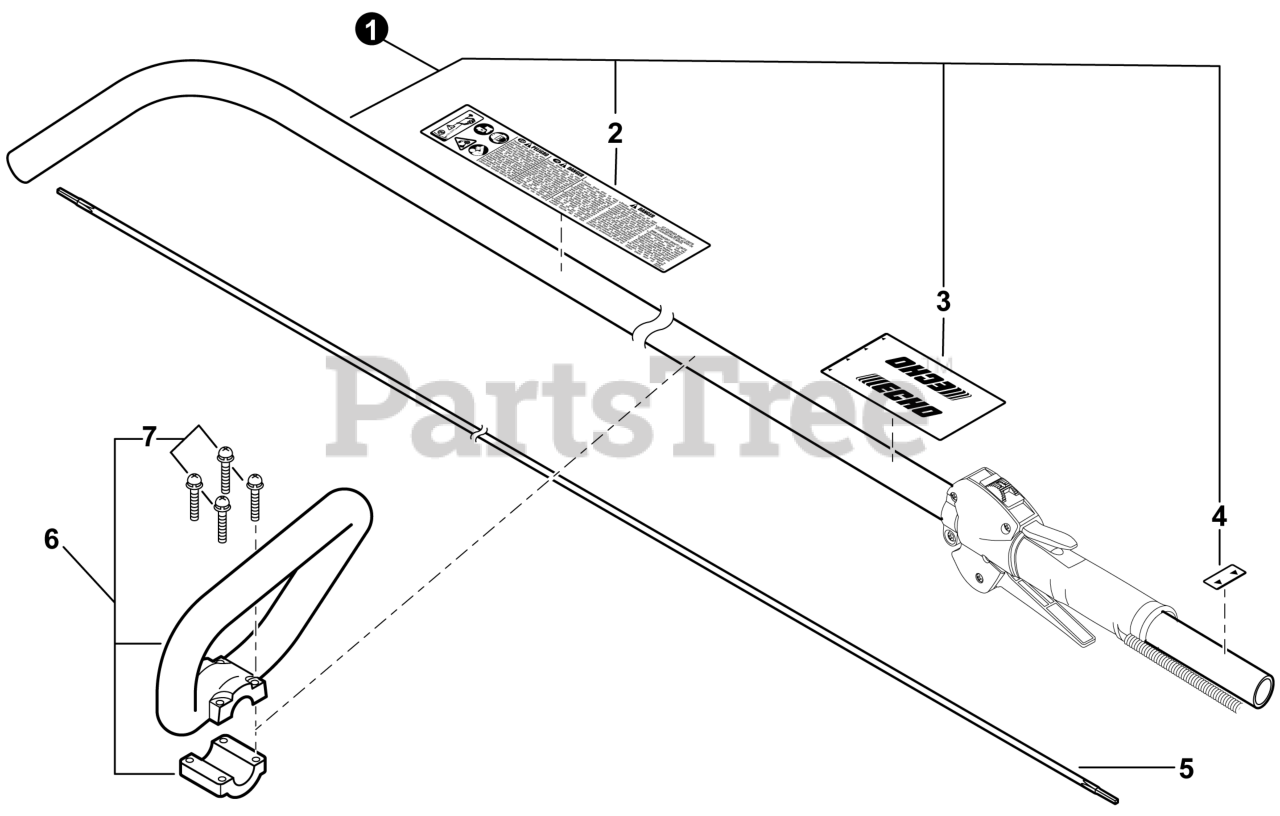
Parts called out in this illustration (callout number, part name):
1	PIPE, MAIN
2	LABEL - ISO CAUTION
3	LABEL - HANDLE LOCATION
4	LABEL - ALIGNMENT
5	DRIVESHAFT - FLEXIBLE
6	HANDLE ASSY - LOOP
7	SCREW 5x35
